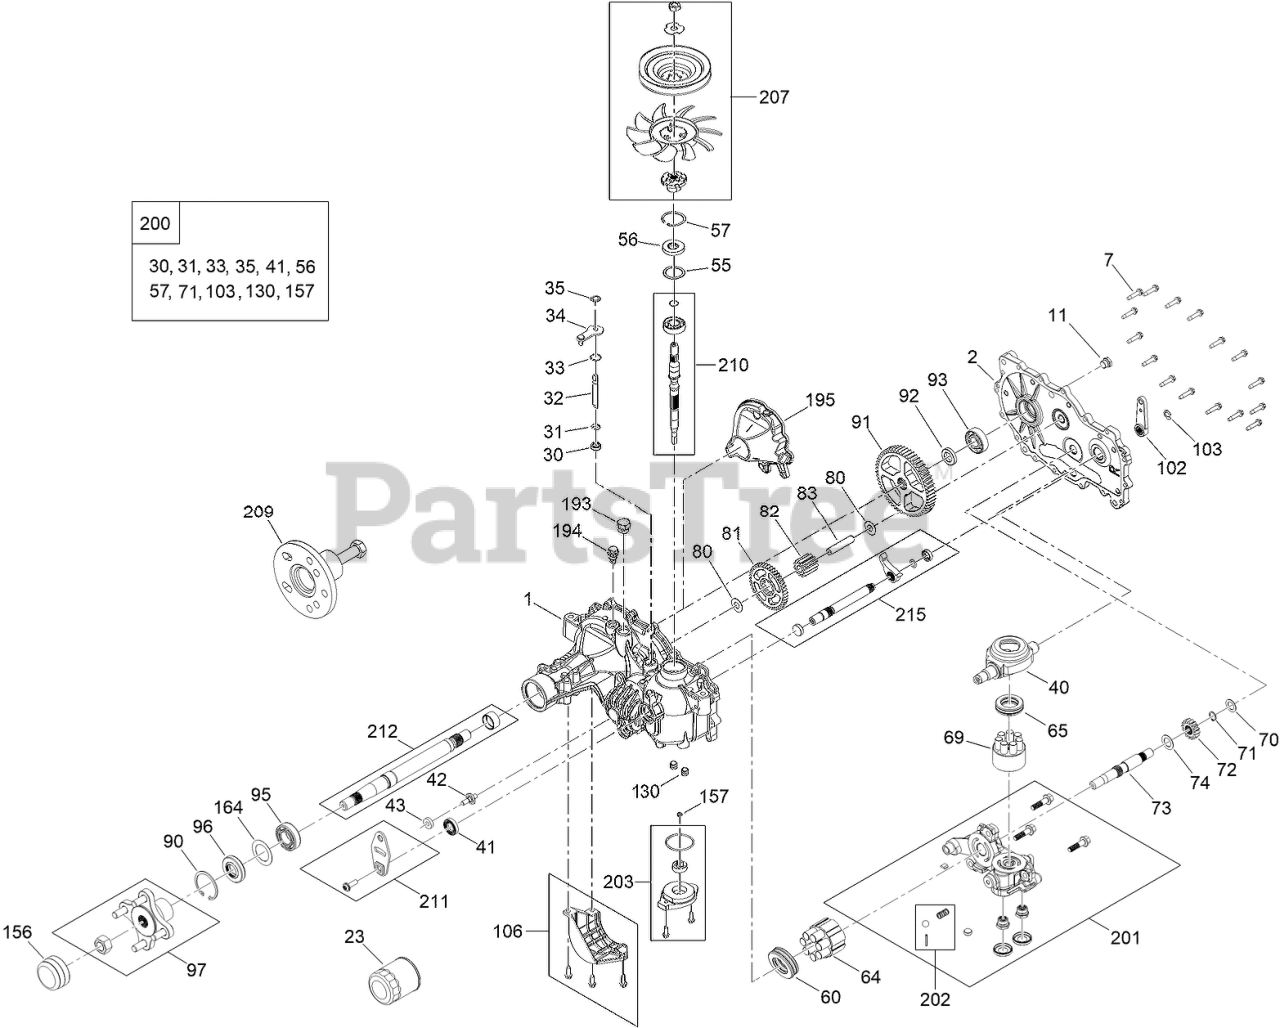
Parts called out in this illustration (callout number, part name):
1	RH MAIN HOUSING KIT
2	RH SIDE COVER KIT
7	SCREW-HHF
23	ELEMENT-OIL FILTER, HYD
30	SEAL-LIP
31	RING-RETAINING, EXTERNAL
32	ROD-BYPASS
33	RING-RETAINING, INTERNAL
35	RING-RETAINING, EXTERNAL
40	SWASHPLATE-TRUNNION
41	SEAL-LIP
43	PUCK-FRICTION
55	SPACER
56	SEAL-LIP
57	RING-RETAINING
60	BEARING-THRUST
64	CYLINDER BLOCK ASM KIT
65	BEARING-THRUST
69	PUMP BLOCK ASM
70	WASHER-FLAT
71	RING-RETAINING
72	GEAR-14T
73	SHAFT-MOTOR
74	WASHER
80	WASHER
81	GEAR-45T
82	GEAR-11T
83	PIN-JACKSHAFT
90	RING-RETAINING
91	GEAR-54T
92	SPACER
93	BEARING KIT
95	BEARING-BALL
97	HUB KIT
102	HANDLE-BRAKE
103	RING-RETAINING, EXT
106	FILTER GUARD KIT
130	TUBE-CHARGE
156	COVER-NUT, AXLE
157	GEROTOR SEAL KIT
164	SPACER
194	BREATHER FITTING ASM
195	RH INTERNAL EXPANSION TANK ASM
200	SEAL KIT
201	RH CHARGE CENTER SECTION KIT
202	CHARGE RELIEF KIT
203	CHARGE KIT
207	FAN AND PULLEY KIT
210	INPUT SHAFT KIT
211	CONTROL ARM KIT
212	AXLE SHAFT KIT
215	INBOARD KIT
